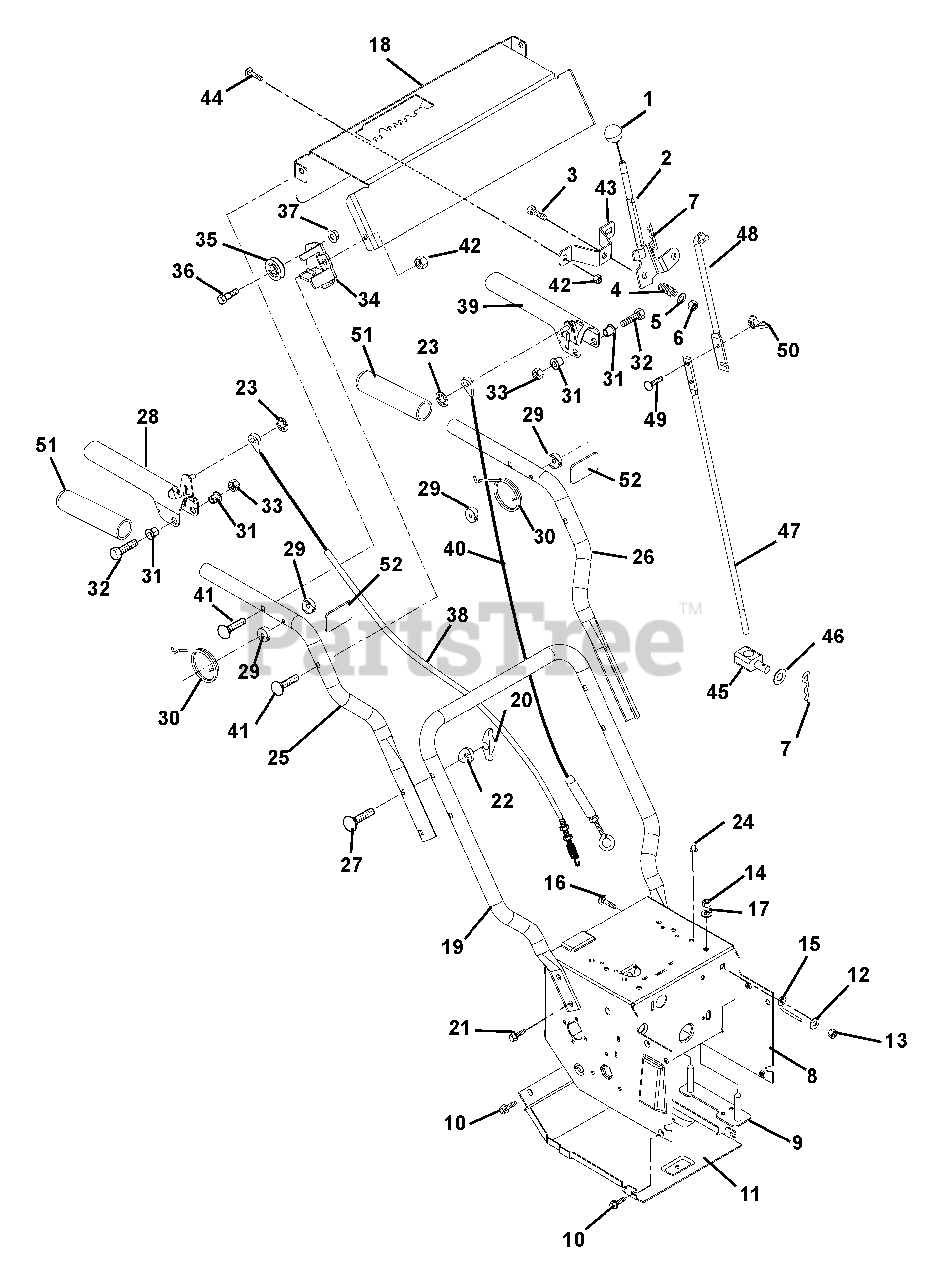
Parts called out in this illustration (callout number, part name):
1	KNOB,BALL -BLACK 1.47" .375-16
2	WMT, SHIFT LEVER
3	@BLT-HEX .38-16X2.00 GR5 YWZC
4	SG-COMP .125X.781X1.250
5	@WSHR-FL-STL.438X1.00X.083 YWZ
6	@NUT-LK-CTR .38-16 YWZC
7	PIN-HAIR INT .08X.18X1.18 YWZC
8	WELDMENT, FRAME - COMPACT SNOW
9	STRAP, ENGINE BOLT-WELDMENT
10	@SCR-TAP .25-20X.37 HWH YWZ TR
11	COVER BOTTOM
12	@WSHR-FL-STL.38X.875X.083 YWZC
13	@NUT-LK-CTR .31-18 YWZC
14	@NUT-HEX .31-18 YWZC
15	BELT FINGER LOWER
16	@BLT-RHDSSQNK .31-18X.75 G5YZ
17	WSHR-LK .312X.097 HVY YWZC
18	CONTROL PANEL W/DECAL
19	HANDLEBAR, LOWER - COMPACT
20	KNOB - WING .312-18 UNC
21	BLT-SERHFWH .38-16X.75 YWZC
22	SPACER, HANDLEBAR
23	RG-RTNG-EXT .250X.010
24	RVT-POP .187X.45 DOME SS FBF64
25	HANDLEBAR, UPPER - RH COMPACT
26	HANDLEBAR, UPPER - LH COMPACT
27	@BLT-RDHDSQNK .31-18X2.25 G5YZ
28	PADDLE, CLUTCH - RH COMPACT
29	BUSHING, .266 X 1.0 X .375
30	SPRING, TORSION
31	BSHG, FLG .266X.42X.150 PM
32	@BLT-HEX .25-20X2.25 GR5 YWZC
33	@NUT-LK-CTR .25-20 YWZC
34	BRACKET, CABLE MOUNT
35	PULLEY, CABLE
36	BOLT, SHLDR-.375X.375X.25-20
37	@NUT-LK-CTR .25-20 YWZC
38	CABLE, AUGER
39	PADDLE, CLUTCH - LH COMPACT
40	CABLE, TRACTION
41	BLT-RDHDXLSQNK .31-18X1.5 G5YZ
42	@NUT-LK-TOP-FLG .31-18 YWZC
43	BRACKET, SHIFT MOUNT
44	@BLT-RHDSSQNK .31-18X.62 G5YZ
45	PIVOT,SHIFT ROD .375-16(TRUNN)
46	@WSHR-FL-STL.281X.62X.065 YWZC
47	ROD, SHIFT - LOWER
48	ROD, SHIFT - UPPER
49	@BLT-RDHDSQNK .25-20X.75 G5YZ
50	NUT-LK WING .250-20 YWZC
51	HANDLE GRIP
52	BUMPER PAD
